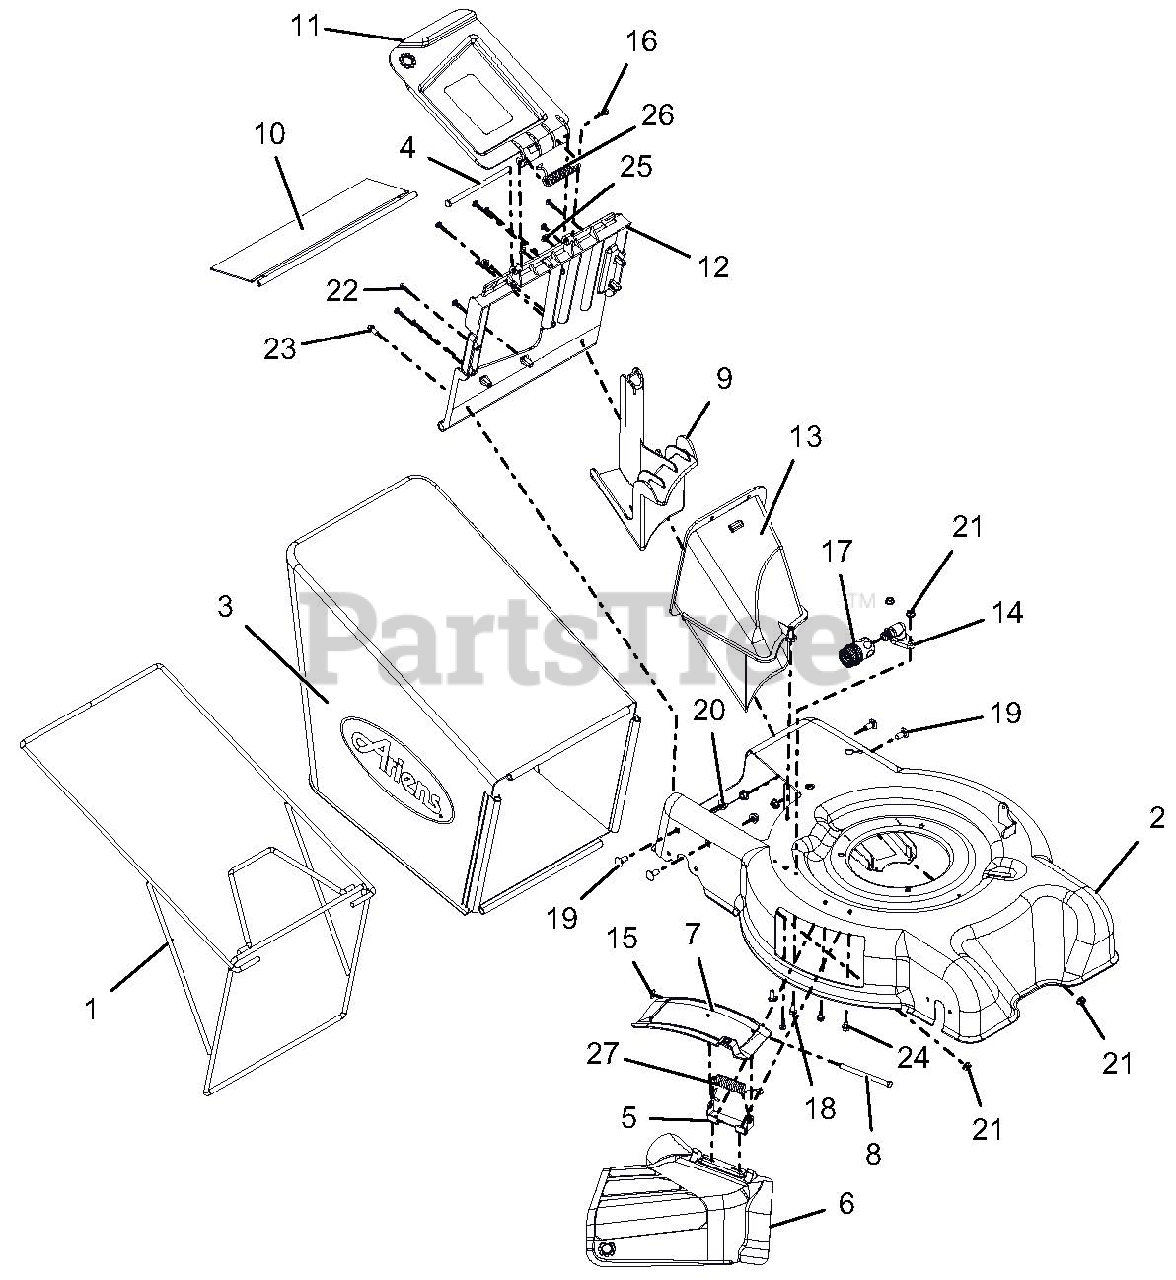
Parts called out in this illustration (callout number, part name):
1	FRAME, BAGGER
2	WLDMT, ARIENS WP DECK
3	BAGGER, ARIENS LM
4	PIN, 5/16 X 5.80"
5	BRKT, HINGE LM
6	CHUTE, SIDE DISCHARGE - LM
7	COVER, SIDE DISCHARGE - LM
8	PIN, HINGE
9	PLUG, MULCH
10	GUARD, REAR DECK
11	REAR DOOR W/ SAFETY DECAL
12	HANGER, REAR BAG
13	CHUTE, REAR DISCHARGE LM
14	ASSY, WASHOUT PORT W/ O-RING
15	NUT-PUSH .312
16	PIN-HAIR INT .08X.18X1.18 YWZC
17	COUPLING, QUICK DISCONNECT
18	BLT-HEX .25-20X.63 GR5 YWZC
19	@BLT-RDHDSQNK .31-18X.75 G5YZ
20	@NUT-LK-TOP-FLG .31-18 YWZC
21	@NUT-LK-TOP-FLG .25-20 YWZC
22	SCR-TAP 12-14X.75PLSTITE @BLZC
23	@SCR-TAP .25-20X.62 HWH TR YWZ
24	@SCR-TAP .25-20X.37 HWH YWZ TR
25	PLUG,5/16 HOLE,.125 MATL PLSTC
26	SG-TORS .120X.68X3.09
27	SPRING, SIDE DISCHARGE DOOR
